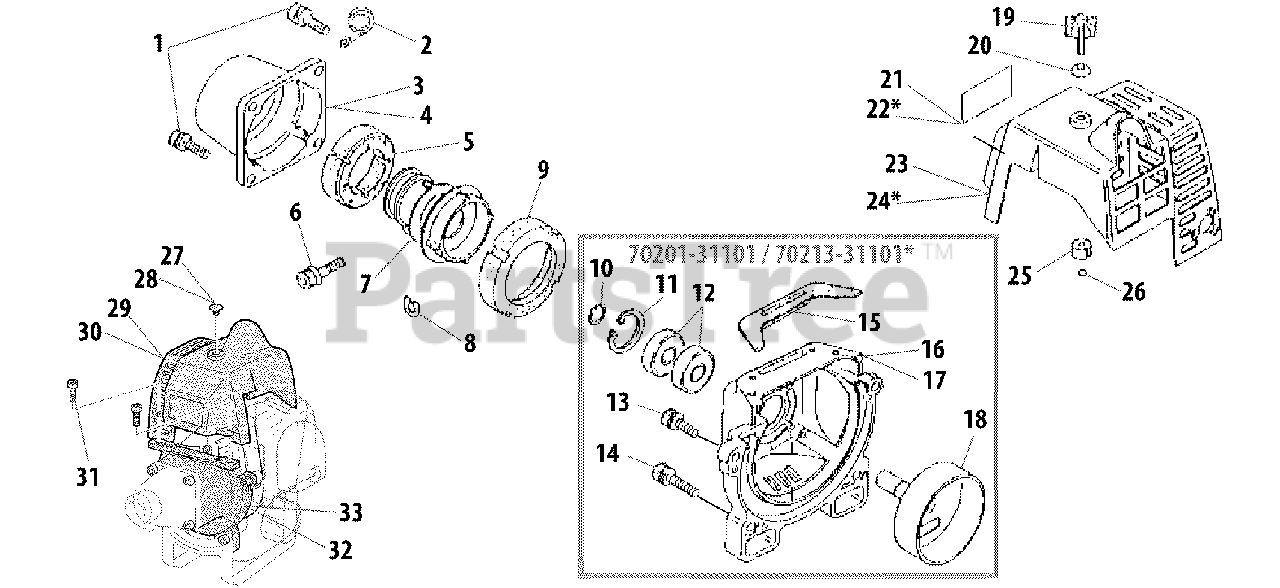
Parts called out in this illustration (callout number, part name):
1	SCREW - 5X20
2	GUIDE, CABLE
3	CAP
4	CAP
5	CUSHION - FRONT
6	SCREW - 5X25
7	CLAMP, MAIN PIPE
8	SHIM
9	CUSHION - REAR
10	RING, RETAINING
11	RING, RETAINING - 26
12	BEARING, BALL - 6000
13	SCREW - 5X25
14	SCREW - 5X16
16	COVER, FAN
17	CASE, FAN - BLUE
18	DRUM, CLUTCH
19	THUMBSCREW
20	WASHER - CONICAL
21	LABEL - MODEL
23	COVER, ENGINE
24	COVER, ENGINE - BLUE
25	INSULATOR
26	CLIP
27	PLUG
28	PLUG - BLUE
29	COVER, ENGINE
30	COVER, ENGINE - BLUE
31	SCREW - 5X16
32	CASE, FAN - RED
33	CASE, FAN - BLUE
A	FAN CASE ASSY - RED
A	FAN CASE ASSY - BLUE
